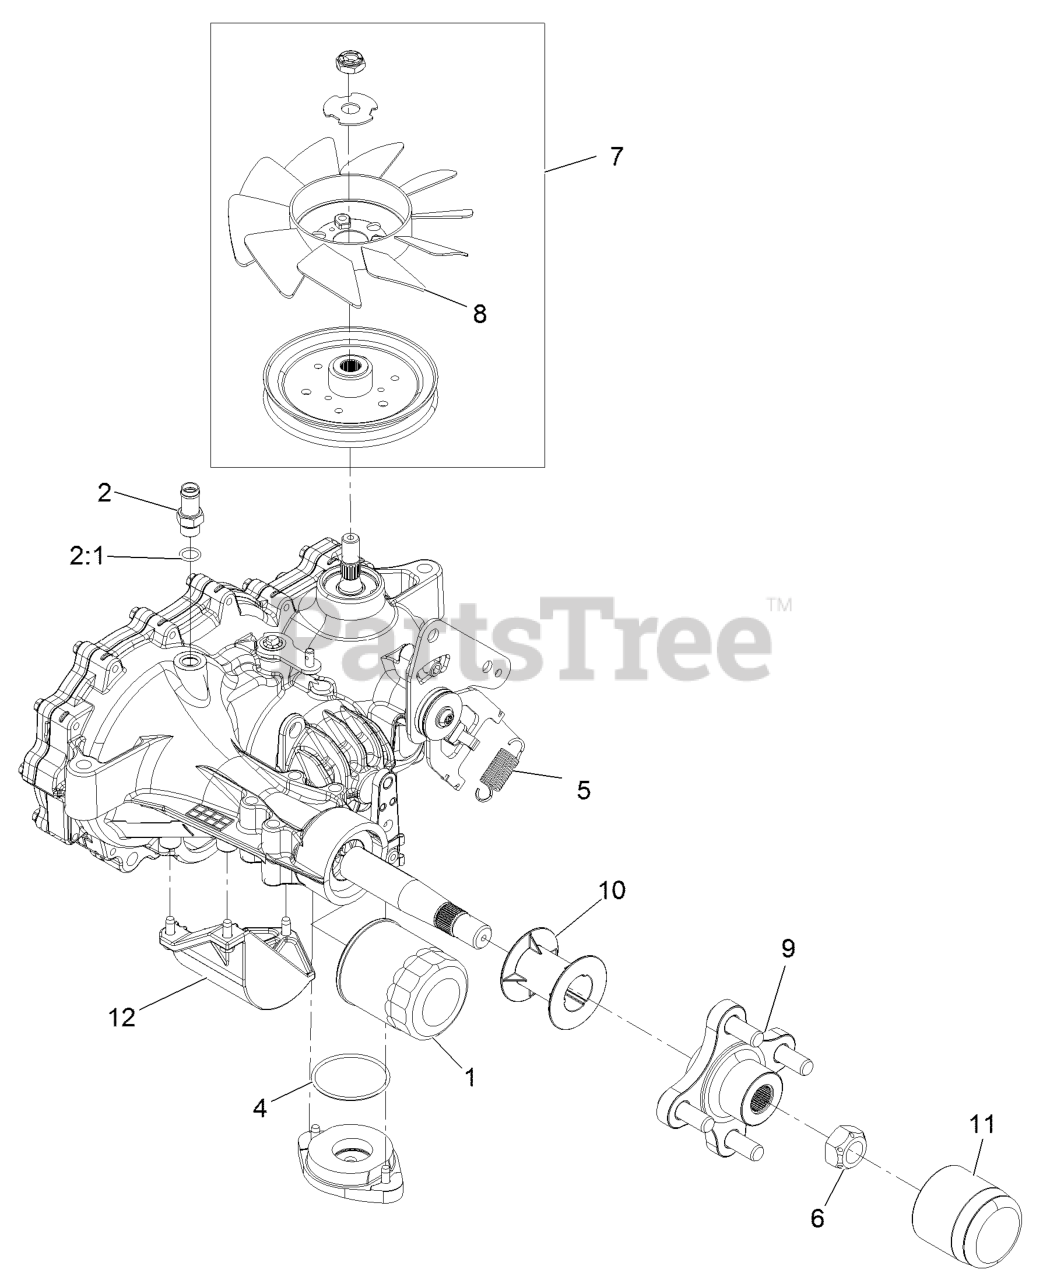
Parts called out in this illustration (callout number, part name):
1	ELEMENT-OIL FILTER, HYD
2	ADAPTER-STRAIGHT
2:1	O-RING
4	O RING-SEAL
5	SPRING-EXTENSION
6	NUT-HUB
9	HUB-OFFSET
10	TUBE-AXLE
11	CAP-AXLE, LONG
12	GUARD-FILTER, RH
